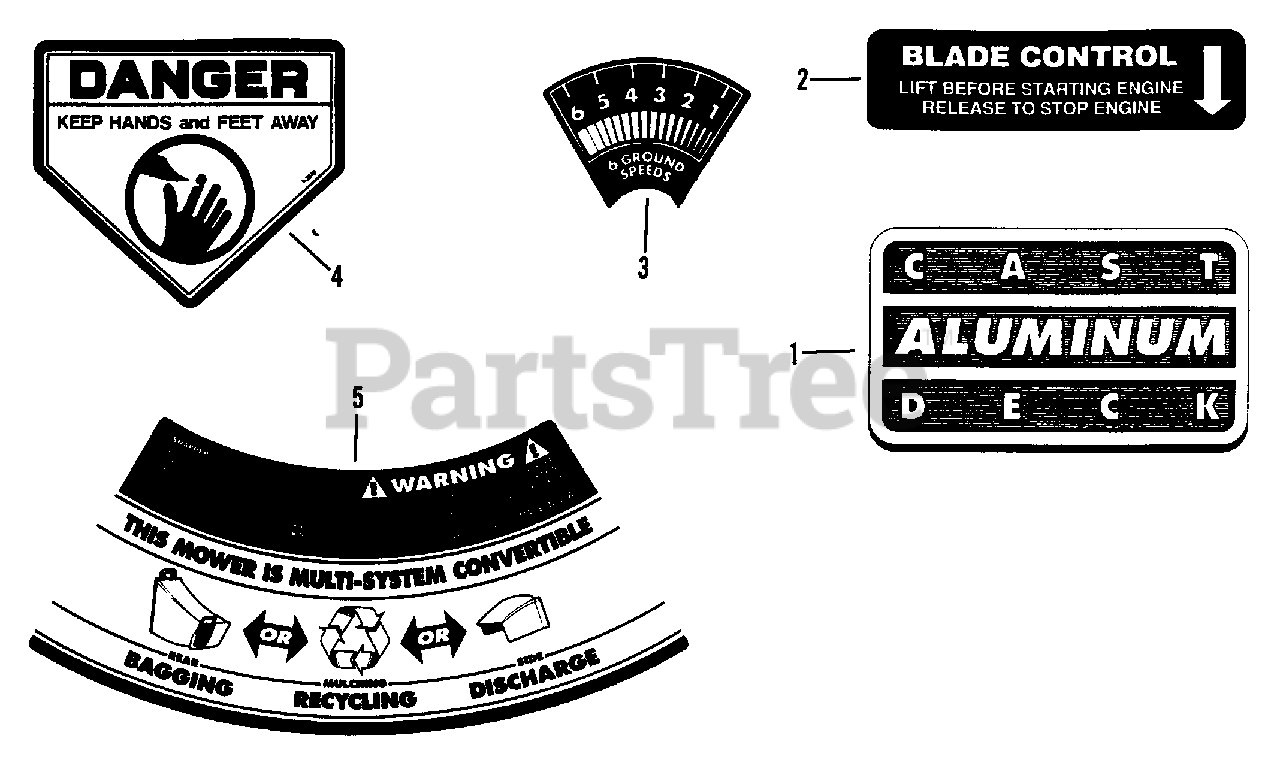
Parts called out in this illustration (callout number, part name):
1	DECAL, Cast Aluminum
2	DECAL, Blade Control
3	DECAL, Speed Sector
4	DECAL, Danger
5	DECAL, Convertible
